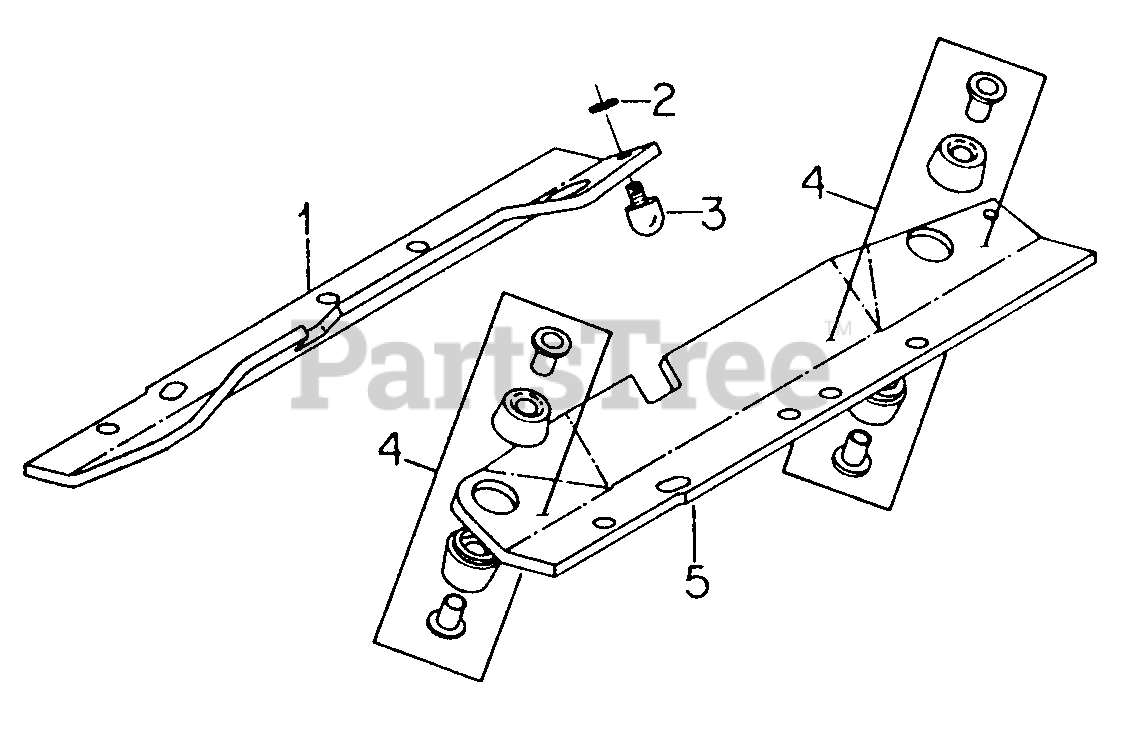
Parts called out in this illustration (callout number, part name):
1	Frame, Engine Mount LH
2	Shim, Snubbing Mount
3	Mount, Snubbing
3	Nut, 1/4 Type 5
4	Mounting Kit, Engine
4	Screw, 3/8 X 2-1/4 Type 5
4	Nut, Hex Center Lock, 3/8-16 GR5
5	Frame, Engine Mount RH
